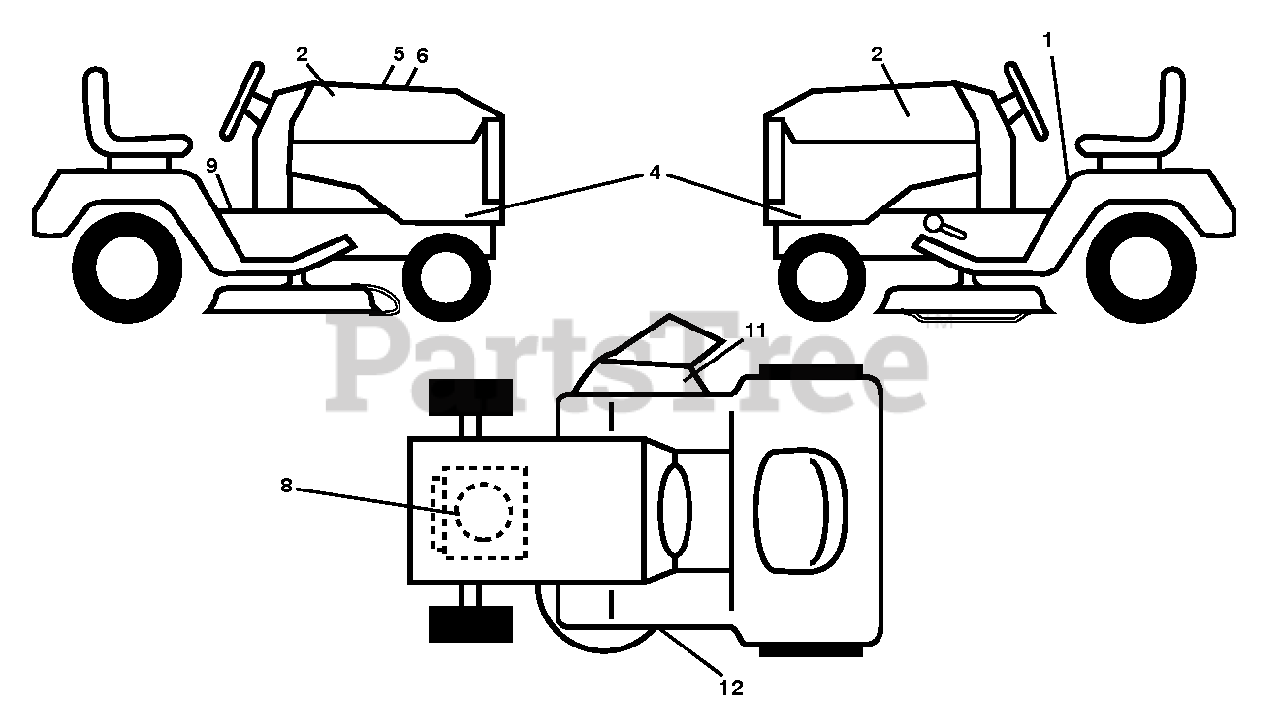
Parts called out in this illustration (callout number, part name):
1	DECAL.FENDER.WARNING.ENG
2	DECAL.HOOD.LOGO.ORANGE.HUSQVAR
4	Decal, Hood Panel
5	DECAL HOOD CUST. RESP.
6	Decal, Replacement LTH1438
8	Decal, Engine B&S 13 5HP IC/OHV
9	DECAL BTRY SYMBOLS
11	DECAL.WARN.KEEP.HAND.AWAY
12	DECAL.V-BELT.SCHEMATIC.36/38/9
